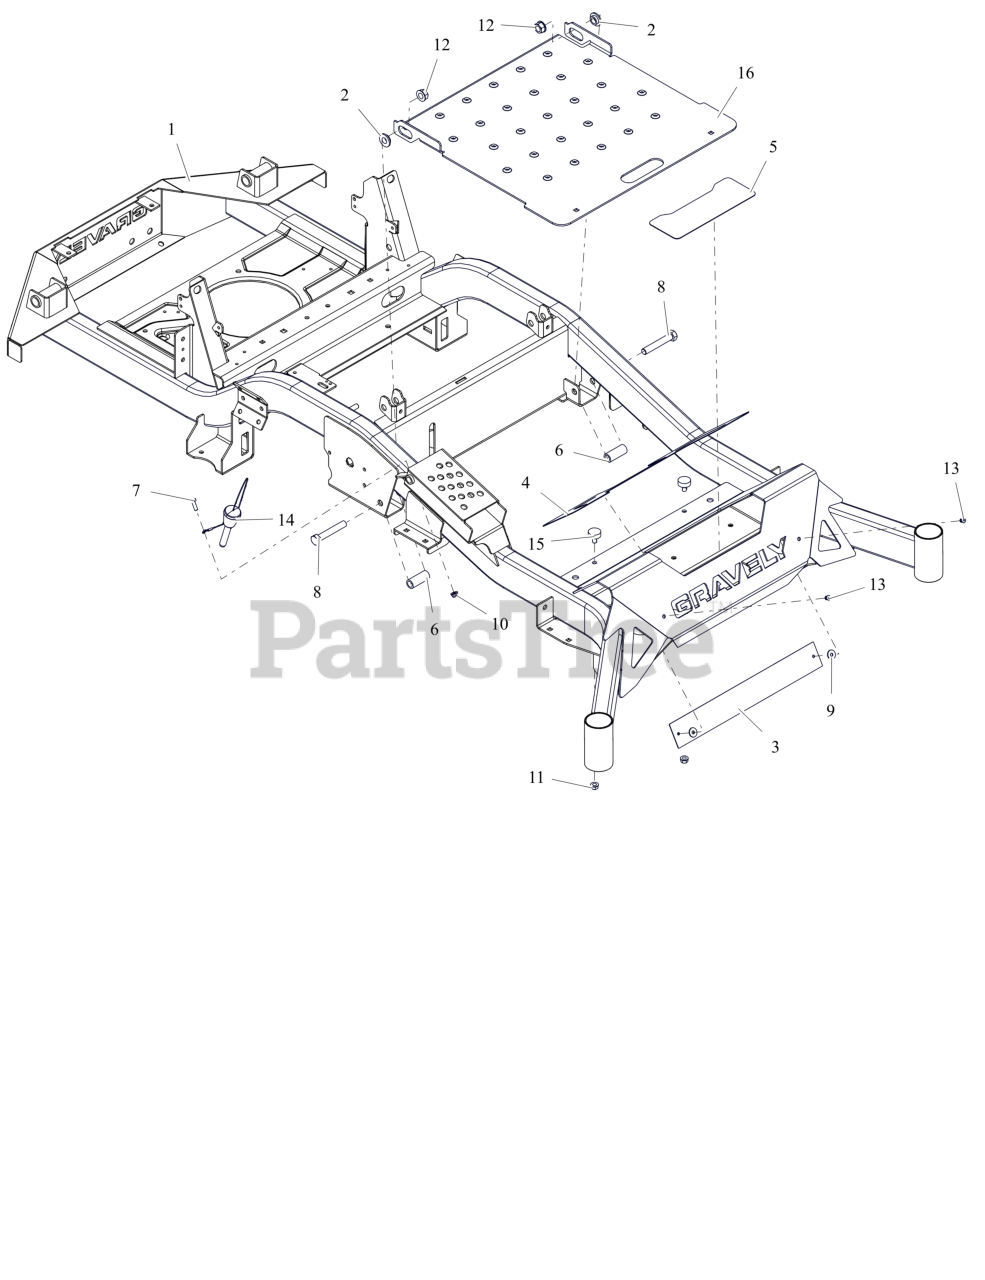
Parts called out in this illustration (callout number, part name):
1	WLDMT, MAIN FRAME -HD 60 (RED)
2	BSHG-FLG .515X.750X.310X1.120
3	PLATE, BACK FOOT-REST XL
4	GRIP, FRONT
5	GRIP, STEP
6	SPACER, .515X.75X1.83
7	BLT, HEX .25-20X.75 G5 ZCC
8	BLT, HEX .50-13X3.00 G5 ZCC
9	WSHR, RBR W/ADHESIVE .25X.75X.06
10	NUT,NYL-FLG .25-20 GF ZCC
11	NUT,SPNLK-FLG .31-18 G5 ZCC
12	NUT-LK-TOP-FLG .500-13 GF ZCC
13	RIVET, .1875 AL/AL .126-.250
14	PIN, MAGNETIC .50X2.50
15	BUMPER, RUBBER
16	KIT,ACCESS PANEL W/DECALS-RED
